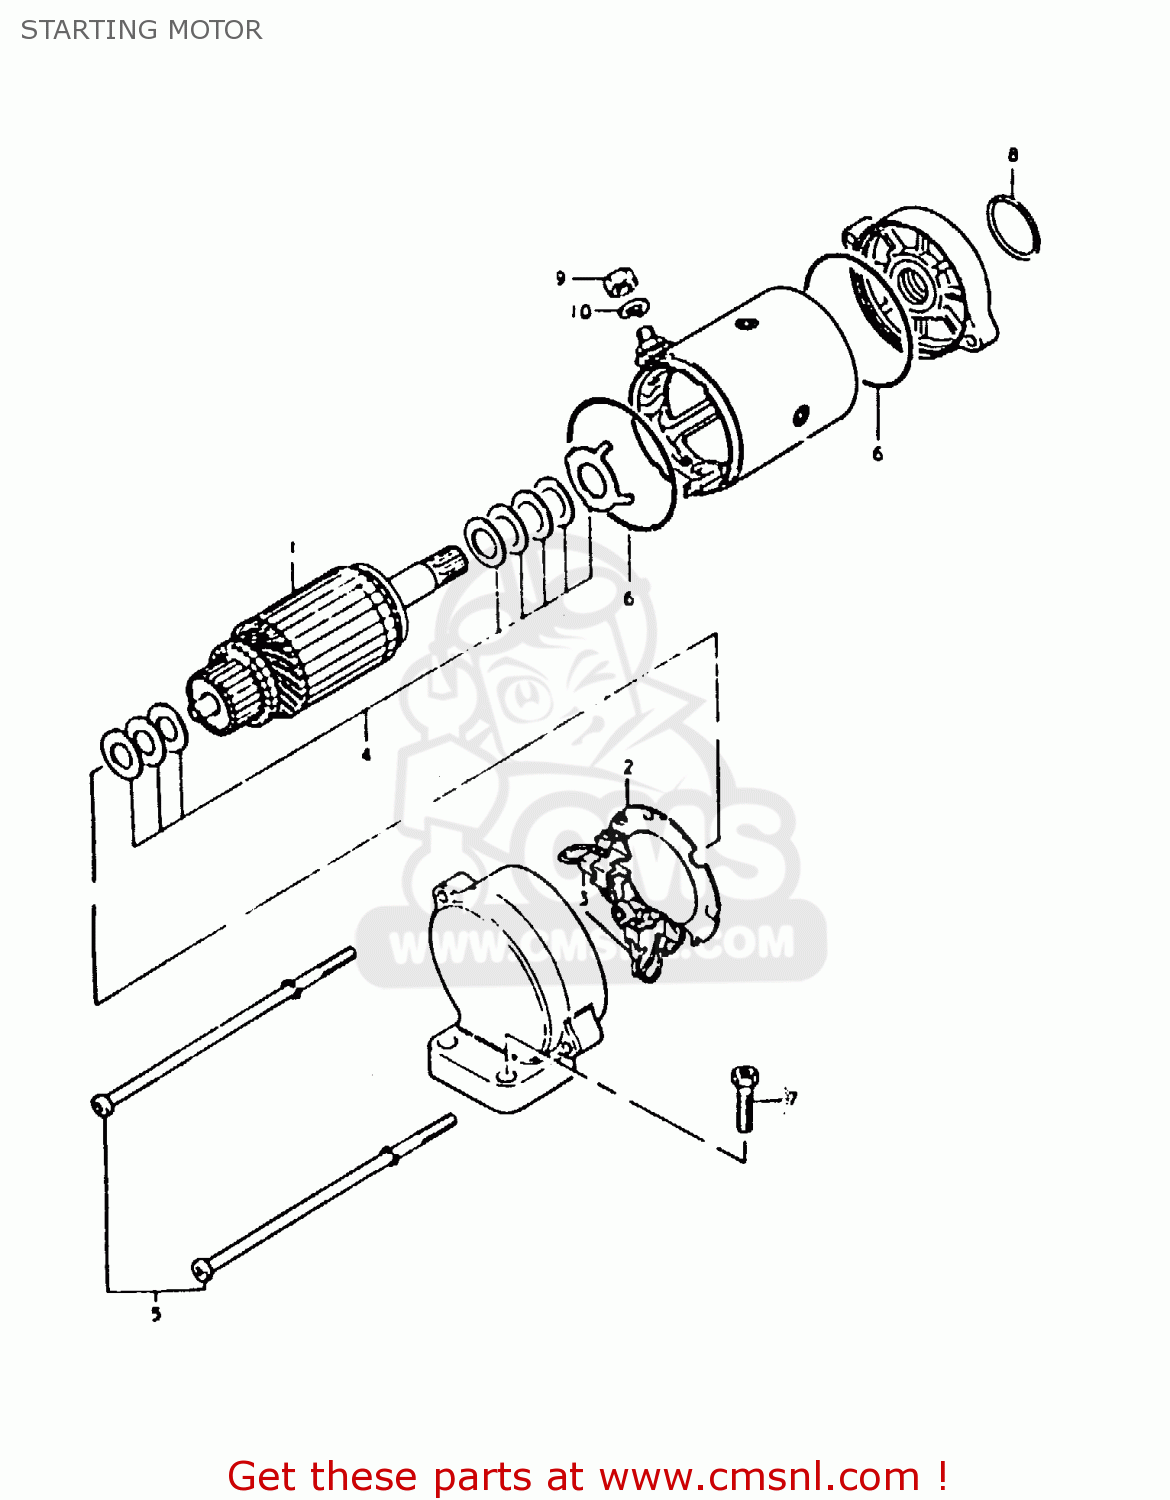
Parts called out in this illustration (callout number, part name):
1	ARMATURE
2	HOLDER ASSY
3	BRUSH SET
4	SHIM SET
5	BOLT,STARTING MOTOR HOUSING
6	O RING
7	SCREW
8	O RING(D:2,ID:24.5)
9	NUT 6MM
10	LOCK WASHER
